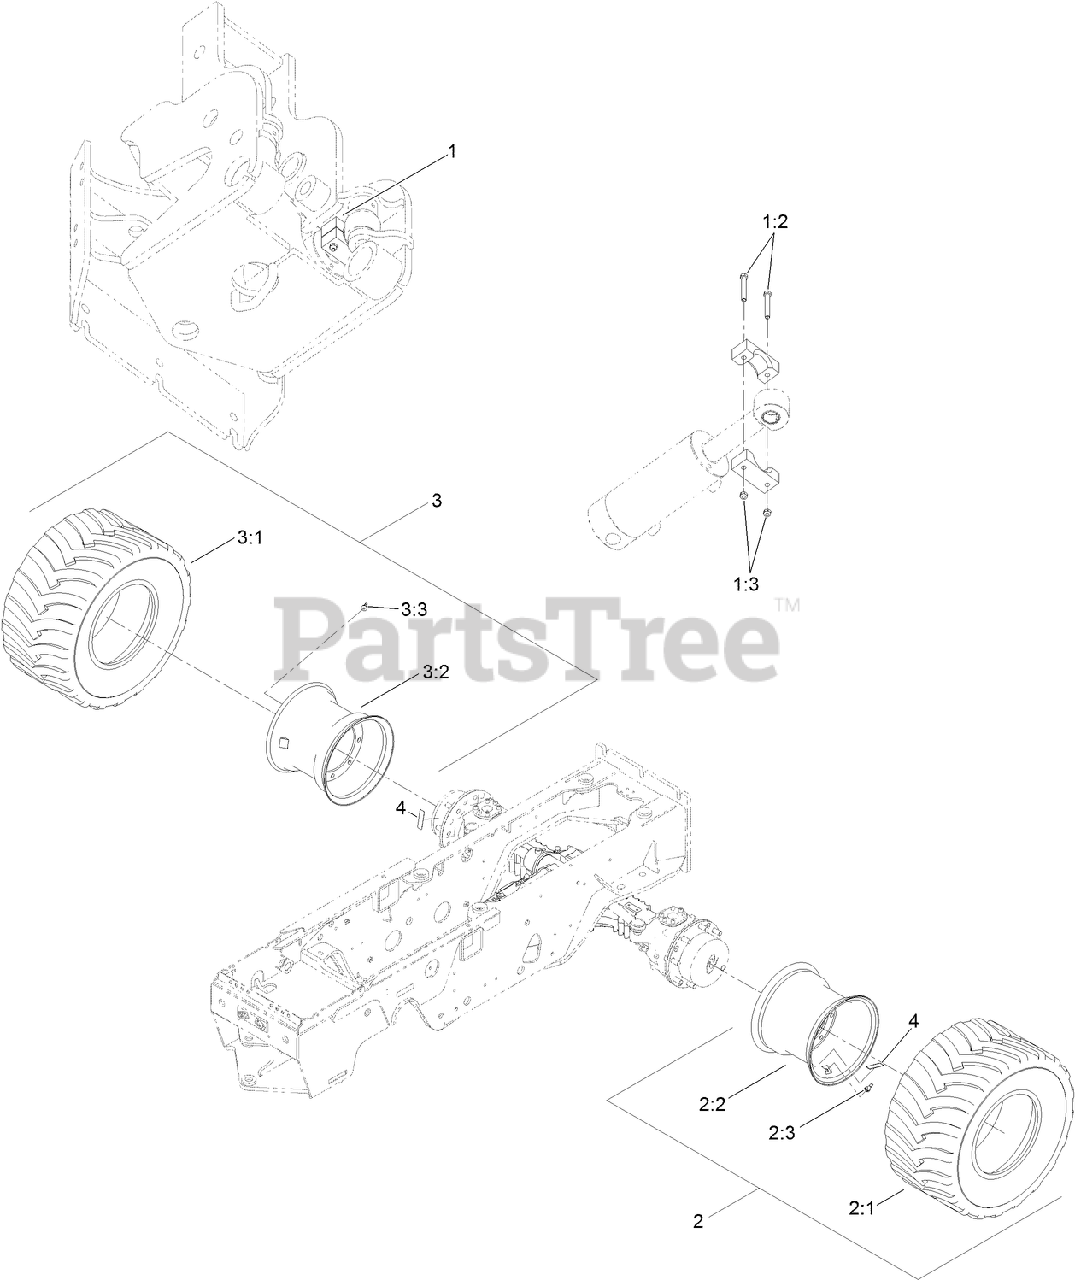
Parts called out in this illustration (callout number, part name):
1	Plow Swing Cylinder Stop ASM
1:2	SCREW-HH
1:3	NUT-HEX
2	RT600 HD TIRE ASM (LEFT)
2:1	TIRE-31X15.50-15NHS (10 PLY)
2:2	WHEEL ASM
2:3	STEM-VALVE
3	RT600 HD TIRE ASM (RIGHT)
3:1	TIRE-31X15.50-15NHS (10 PLY)
3:2	WHEEL ASM
3:3	STEM-VALVE
4	DECAL-REAR WHEEL ONLY
